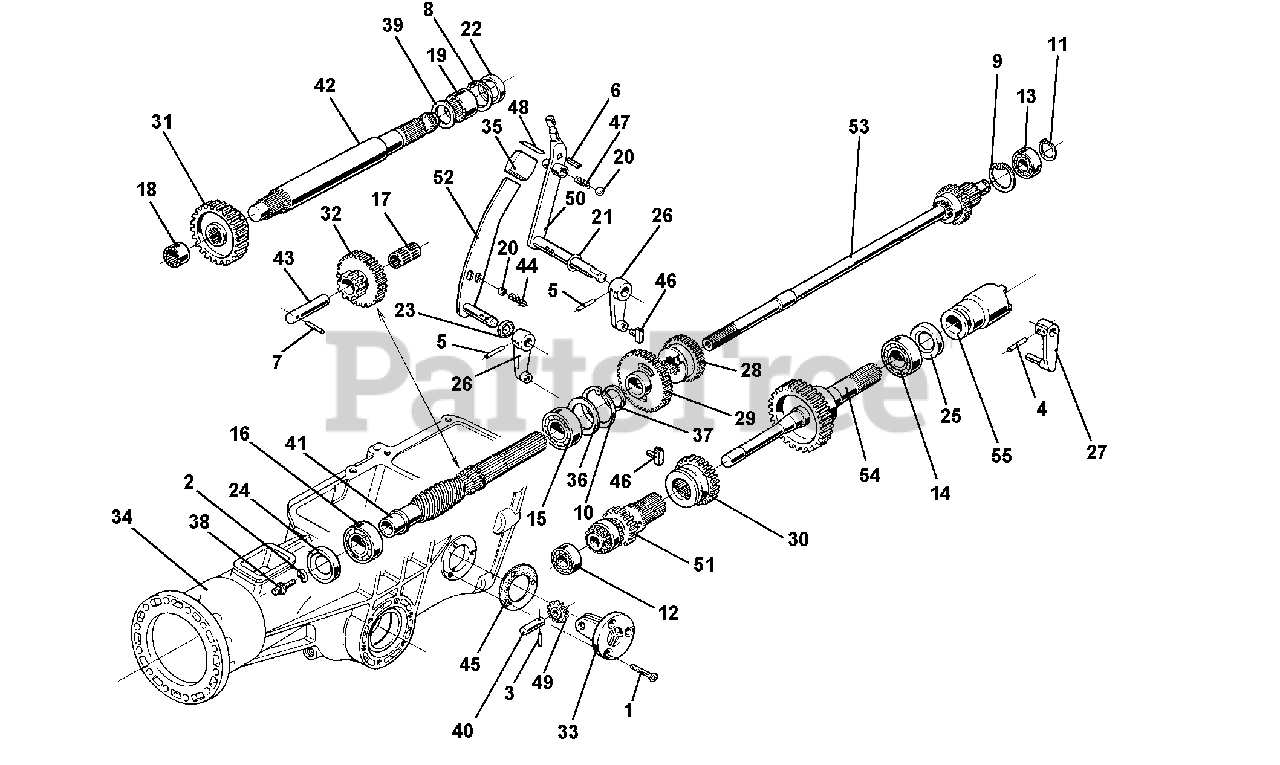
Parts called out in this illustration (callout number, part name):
1	SCREW M6 X 16
2	WASHER, LOCK 8.4
3	PIN, LOCKING 2.5 X 22 DIN 1481
4	LOCKING PIN 4 X 20 SPIRAL
5	LOCKING PIN 4 X 24 SPIRAL
6	LOCKING PIN SPIRAL
7	PIN 4 X 45 SPIRAL
8	CIRCLIP, INTERN D 37 DIN 472
9	CIRCLIP, INTERN D 42 DIN 472
10	CIRCLIP, INTERN D 52
12	BEARING 15 X 35 X 11 6202
13	BEARING 15 X 42 X 14 6302
14	BEARING 25 X 52 X 15 6205
15	BEARING SKF 25 X 52 X 15 6205
20	BALL 15/32 RIV RB-11.906
21	O-RING 115 11.91 X 2.62
23	SEAL, OIL 12 X 19 X 5 STANDARD
24	SEAL, OIL 15 X 40 X 10 STANDARD
25	OIL SEAL 25 X 40 X 7
26	LEVER, SPEED CHG SLDG GR
27	SLIDE LEVER
28	SLIDER SPEEDS
29	WHEELS FIRST SPEED
30	REDUCTION UNIT SLIDER
32	DOUBLE GEAR
33	FLANGE, REVERSE SPEED
34	GEARBOX 745 / 606-605
35	KNOB REDUCTION UNIT LEVER
37	WASHER 25 X 32 X 2 C-72
38	CENTERING SCREW M8
42	SYNCHRONIZED P.T.O. SHAFT
48	PLATE SLOW/FAST SPEEDS
49	REVERSE SPEED GEAR
50	GEARBOX LEVER
51	GEAR TRIPLE
52	LEVER REDUCTION UNIT
53	CLUTCH SHAFT
54	P.T.O. SHAFT
55	P.T.O. COUPLING
